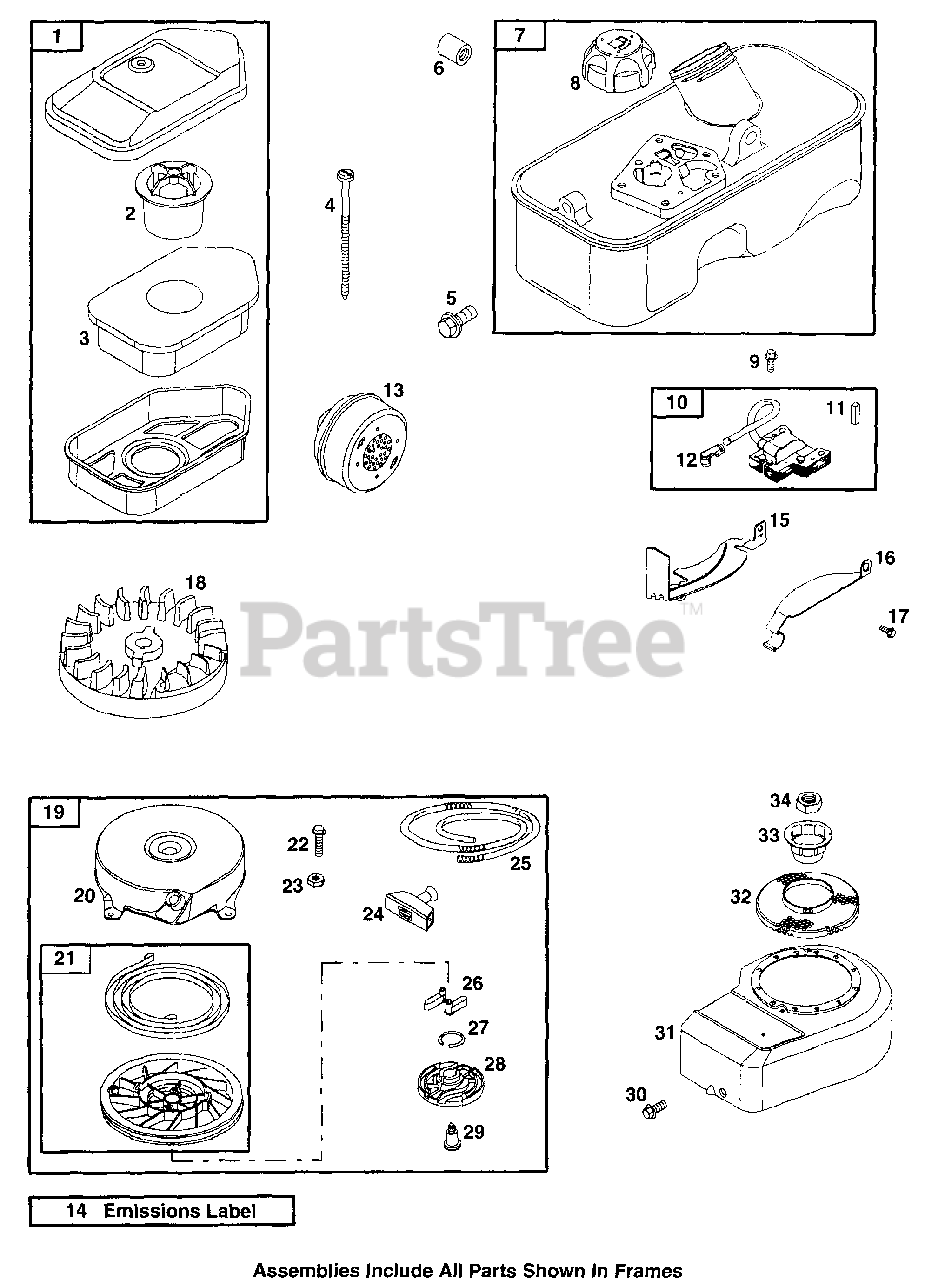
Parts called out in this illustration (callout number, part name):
1	Air Cleaner
2	Foam Element Support
3	Air Cleaner Foam Filter
4	Screw (Air Cleaner)
5	Screw (Fuel Tank)
6	Fuel Tank Spacer
8	Fuel Tank Cap
9	Screw (Magneto Armature)
10	Magneto Armature
11	Flywheel Key
12	Sparkplug Terminal
13	Exhaust Muffler
14	Emissions Label
15	Flywheel Guard (Muffler Side)
16	Flywheel Guard (Carburetor Side)
17	Screw (Flywheel Guard)
19	Rewind Starter
20	Rewind Starter Housing
21	Pulley/Spring Assembly
22	Screw (Rewind Starter)
23	Nut (Rewind Starter)
24	Starter Rope Grip
25	Starter Rope
26	Ratchet Pawl
27	Friction Spring
28	Pawl Friction Plate
29	Screw (Pawl Friction Plate)
30	Screw (Blower Housing)
31	Blower Housing
32	Rotating Screen
33	Flywheel Cup
34	Nut (Flywheel)
